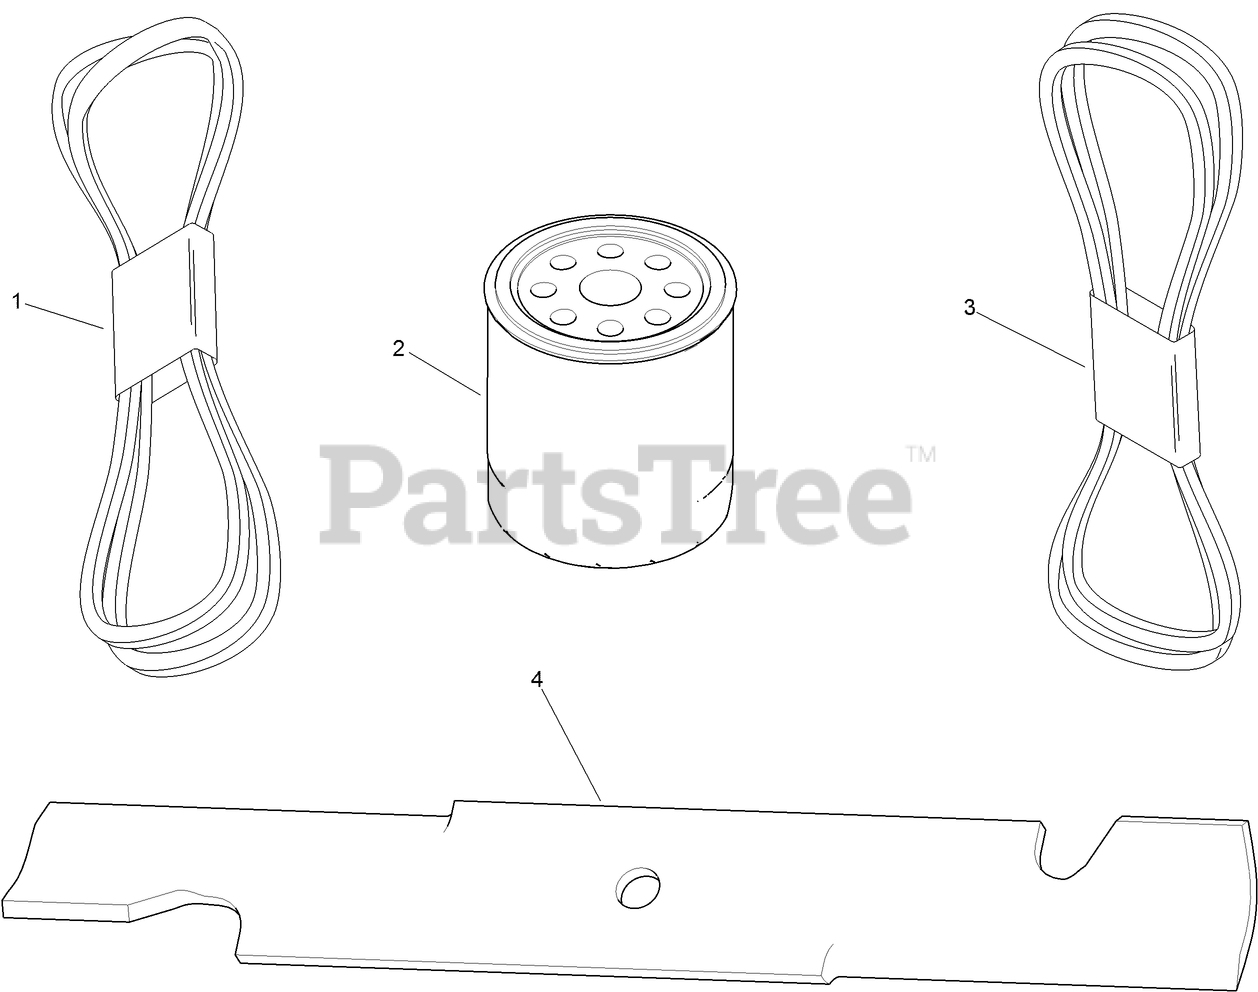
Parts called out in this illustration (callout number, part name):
1	BELT-V, LOWER PTO
2	ELEMENT-FILTER, 25 MICRON
3	BELT-V
4	BLADE-18IN, HI FLOW
